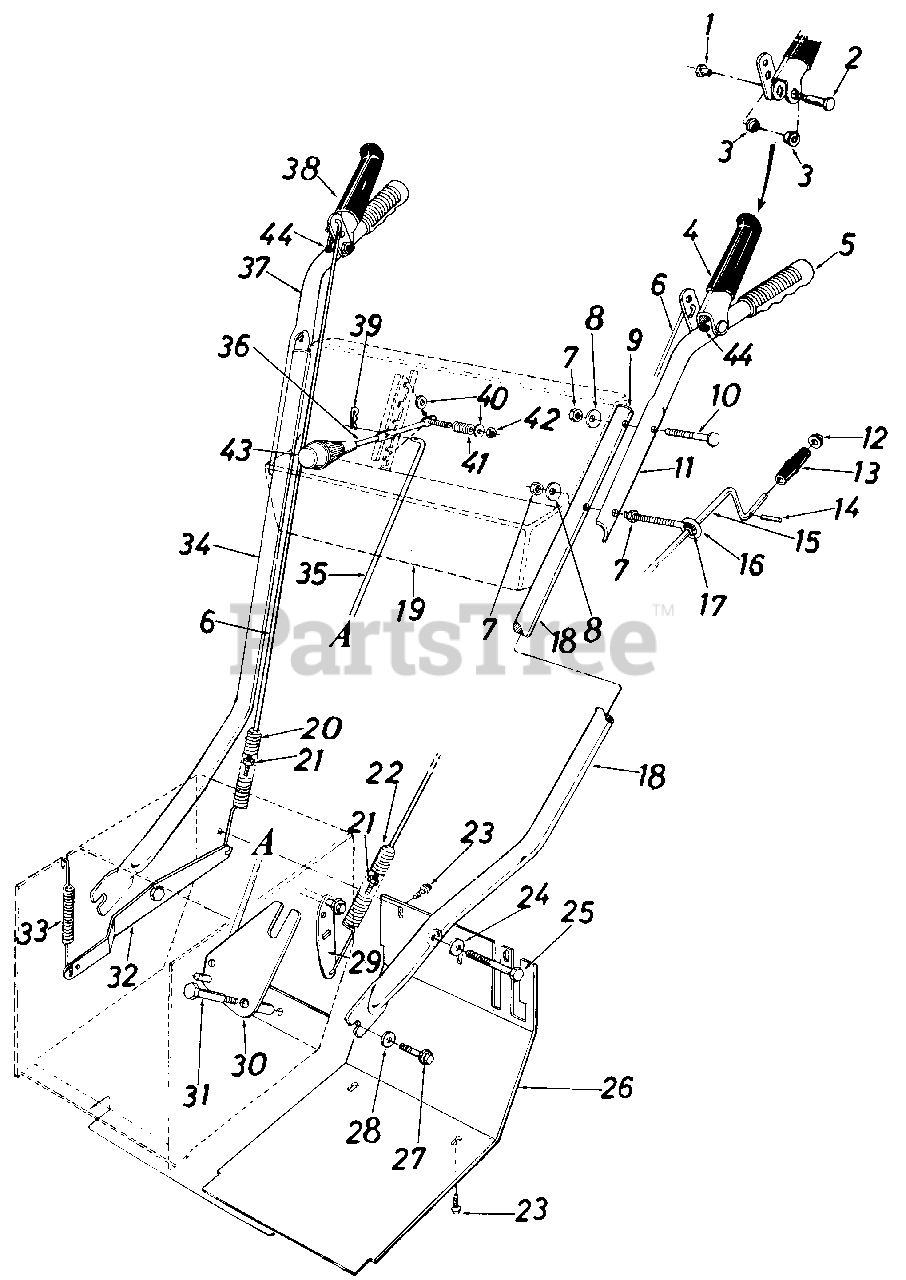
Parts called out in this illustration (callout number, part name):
1	Shld. Nut 1/4-20 Thd.
2	Shld. Bolt .374 Dia. x 1.53"-Lg.
3	Hex Flange Plastic Bearing .38" I.D.
4	Clutch Grip Ass'y.-L.H.
5	Grip
6	Lockout Rod
7	Hex Nut 5/16-18 Thd.*
8	Bell-Wash. .34" I.D. x .88" O.D.
9	Plastic Plug
10	Curved Carriage Bolt 5/16-18 x 2.0" Lg.
11	Upper Handle-L.H.
12	Push Nut 3/8" Rod
13	Knob 3/8" Rod
14	Roll Pin .12 Dia. x .631" Lg.
15	Chute Crank Ass'y.
16	Eye Bolt 5/16-18 x 5.0" Lg.
17	Plastic Bushing
18	Lower Handle-L.H.
19	Handle Panel Ass'y.
20	Extension Spring .75" O.D. x 5.0" Lg
21	Hex Ins. L-Nut 1/4-20 Thd.
22	Extension Spring .75" O.D. x 5.0" Lg.
23	Hex Wash. Hd. Self-Tap Scr. 5/16-24 x .50" Lg.
24	Bell-Wash. .40" I.D. x .88" O.D.
25	Hex Bolt 3/8-16 x 2.0" Lg.
26	Frame Cover
27	Pilot Hex Scr. 3/8-16 x .88"-Lg.
28	Bell-Wash. .40" I.D. x .88" O.D.
29	Drive Clutch Brkt. Ass'y.
32	Auger Clutch Brkt.
33	Extension Spring .38" O.D. x 3.18" Lg.
34	Lower Handle-R.H.
35	Shifting Rod
36	Shift Handle
37	Upper Handle-R.H.
38	Clutch Grip Ass'y.-R.H.
39	Int. Cotter Pin 5/16" Dia.
40	Fl-Wash. .344" I.D. x .62" O.D.
41	Compression Spring
42	Hex Ins. L-Nut 5/16-18 Thd.
44	Push Cap
